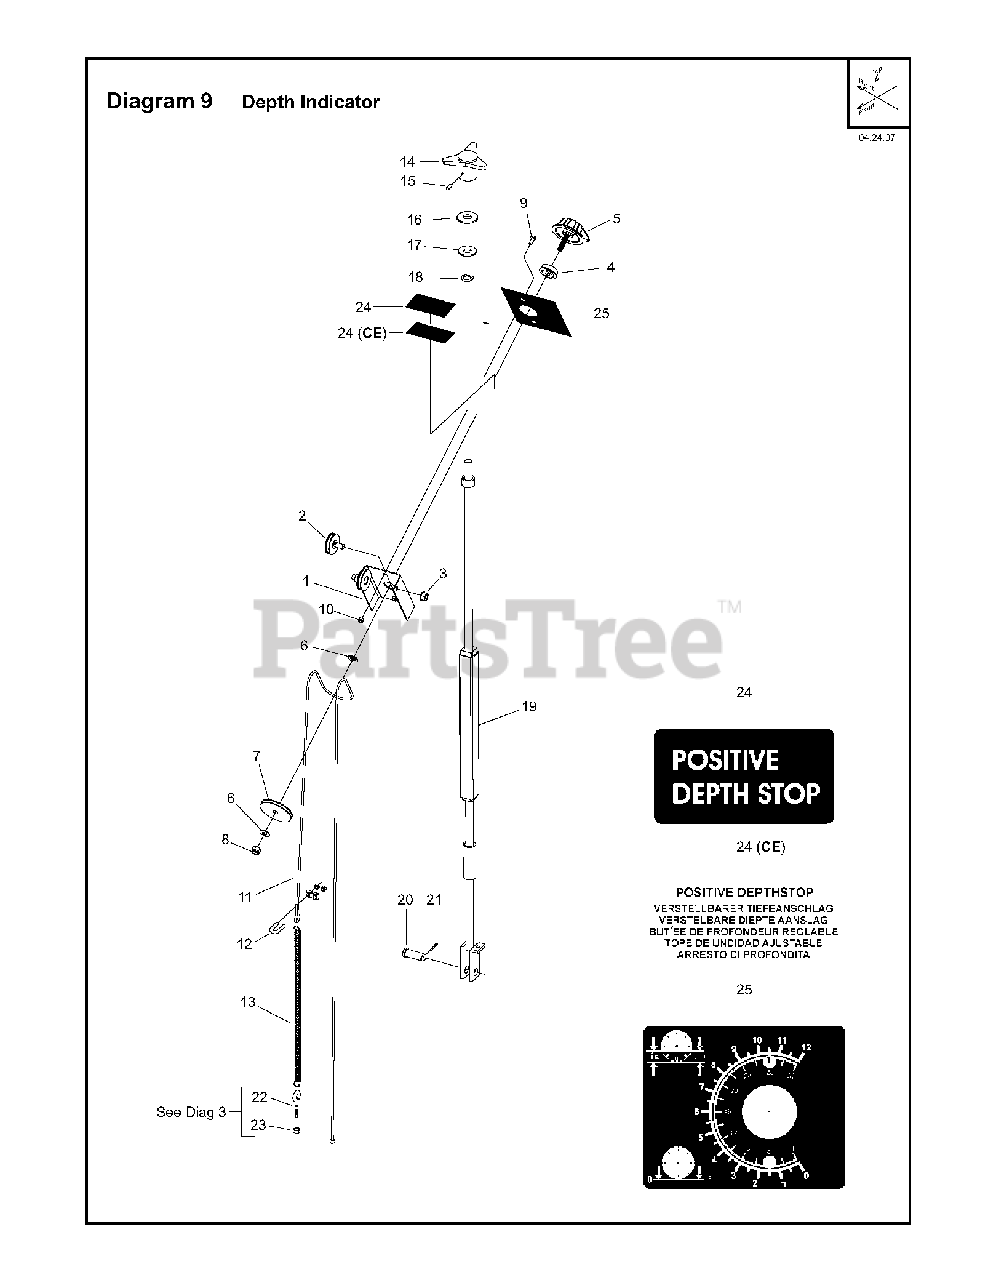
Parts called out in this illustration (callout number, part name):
1	BKT. MTG 16GA X3.875 X5.25
5	DECAL
7	PULLEY DEPTH INDICATOR
8	LOCKNUT. FIBER .3125-18 Z/P
9	PHMS. M5 x 0.8 x 12mm Z/P
10	HEXAGON LOCKING NUT
13	WASHER
18	LOCKWASHER. SPRING
19	DEPTH STOP ASSEMBLY
21	PIN. COTTER .0937 x .75 Z/P
22	EYEBOLT. M6x1.0x50mm OAL
23	NUT
25	DECAL
